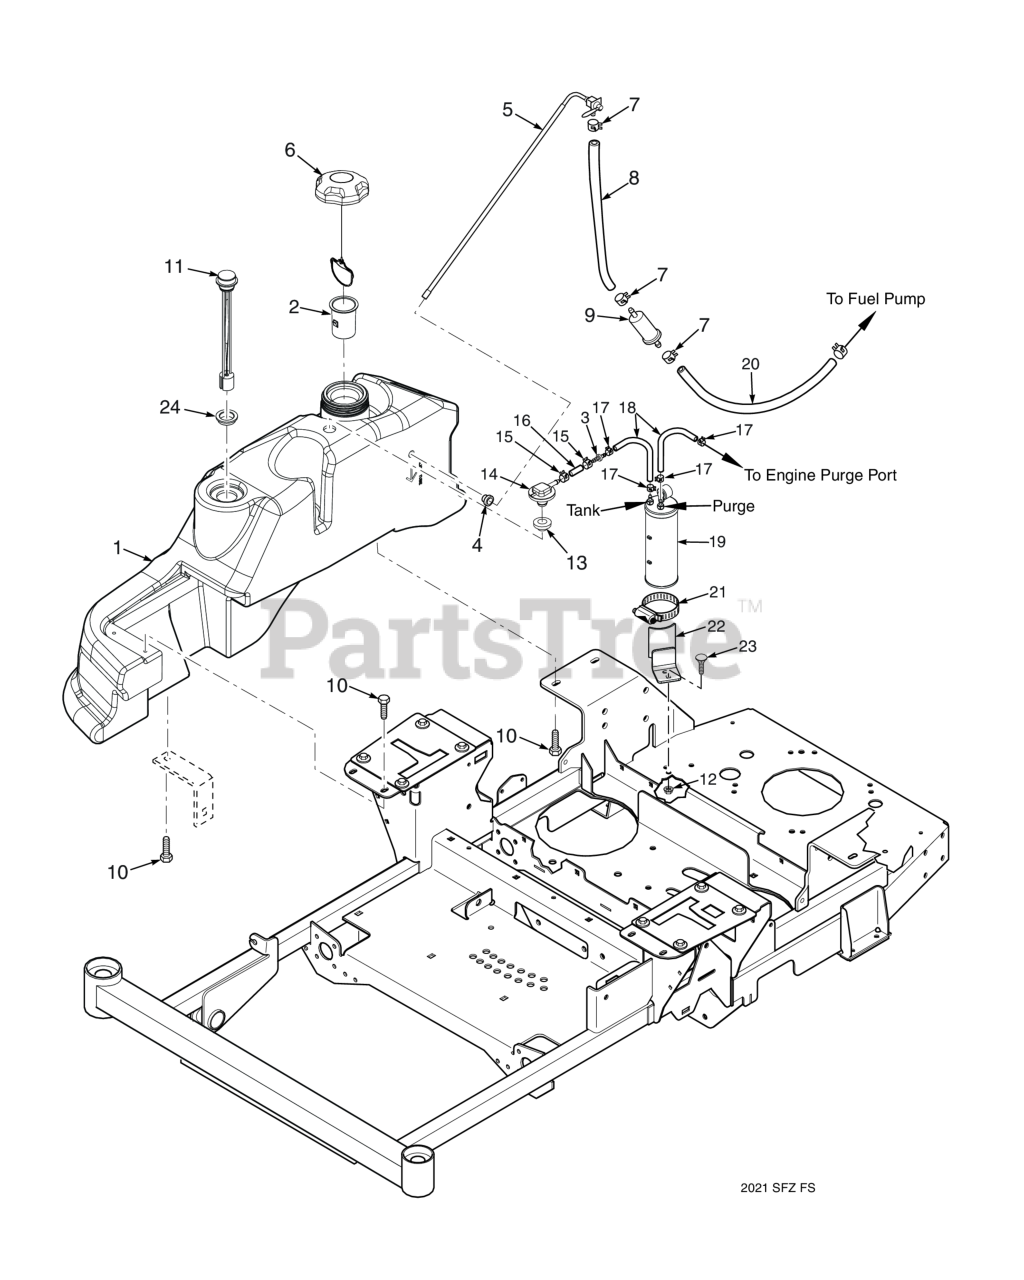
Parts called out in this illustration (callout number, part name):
1	Fuel Tank Assembly
2	Tube, Fuel Tank Insert - 4"
3	Mender, 1/4 x 3/16 w/0.02 Hole
4	Bushing, 0.56" Dia. Viton
5	Fuel Tube Assembly
6	Fuel Cap w/ Tether (E.P.A.)
7	Clamp, Fuel Hose 1/4" Hose I.D.
8	Fuel Hose, 1/4" I.D. Non-Perm (791DFI Fuel Return) - Order by Inch
9	Fuel Filter
10	Capscrew, 5/16-18 x .75 Serrated Flange Hex Head
11	Fuel Gauge (requires #6)
12	Nut, Serrated Flange 5/16-18 (Right Front Engine Mounting, Briggs and Kohler Only)
13	Grommet, Viton,
14	Remote Vent, No Valve
15	CLAMP, FUEL HOSE(KAWASAKI ONLY)
16	Hose, 1/4" Vapor Recovery (order by inch)
17	Clamp, Vapor Recovery Hose 3/16"
18	Hose, Vapor Recovery 3/16" (order by inch)
19	Carbon Canister - SVR-52V / SVR-61V
20	Fuel Hose
21	Clamp, 3-1/2" Max. Dia.
22	Bracket Weldment, Kohler Models
23	Bolt, 5/16-18 x .75 RHSN Carriage
24	Grommet, Fuel Gauge
